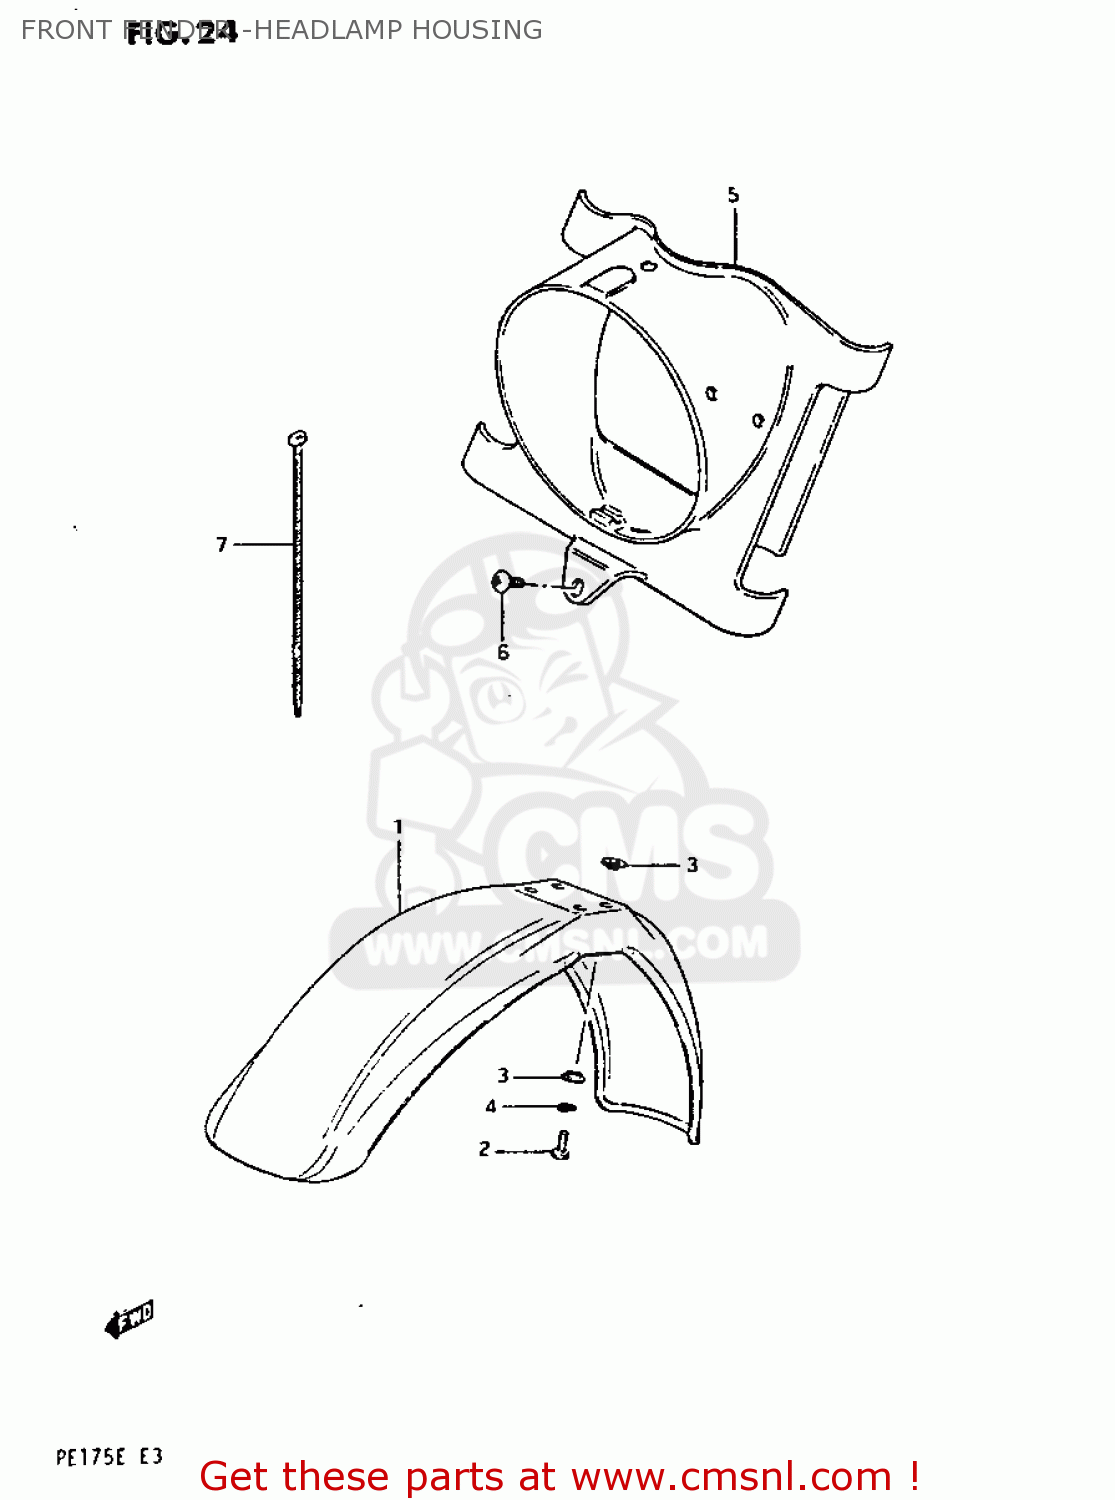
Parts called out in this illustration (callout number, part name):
1	FENDER,FRONT
2	BOLT
3	WASHER
4	WASHER,LOCK
5	HOUSING,HEADLAMP
6	SCREW(5X10)
7	CLAMP
